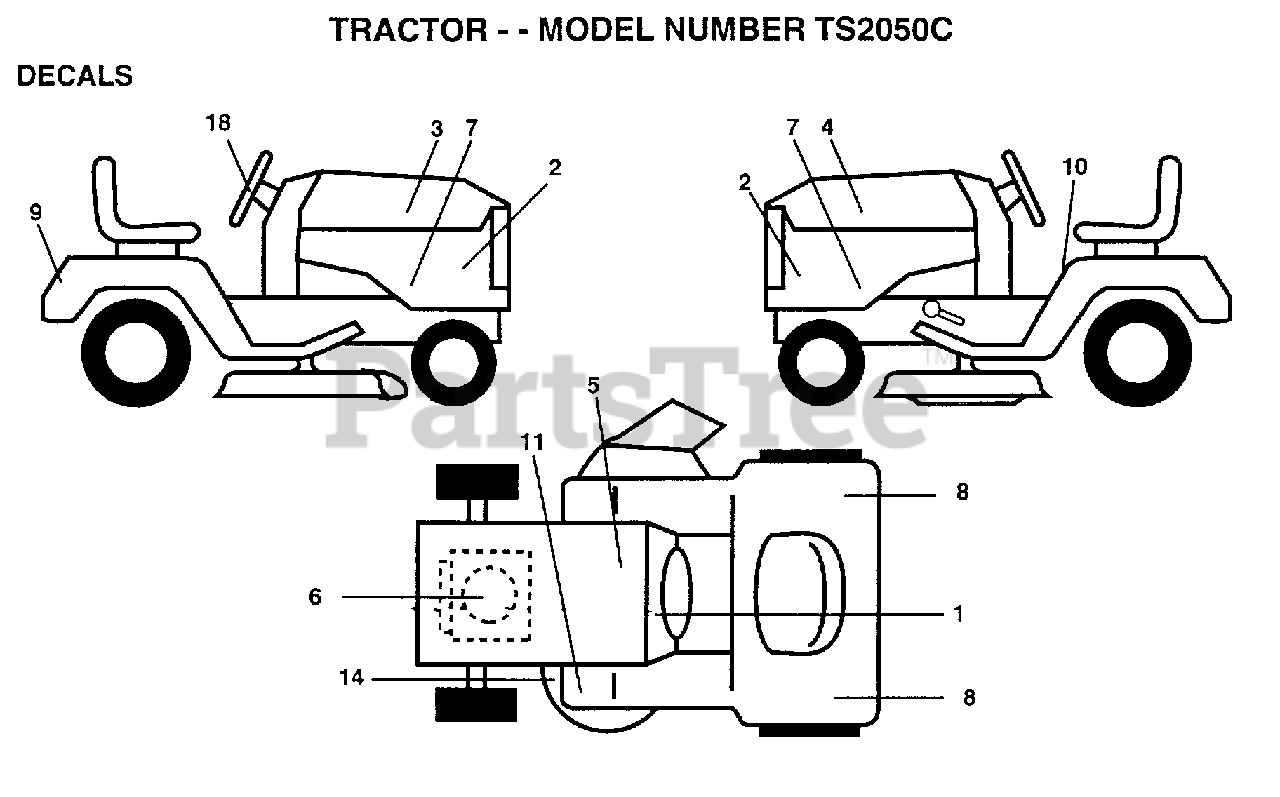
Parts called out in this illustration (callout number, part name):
1	DECAL.DASH.INST.
2	NAMEPLATE.HUSK.LG
3	DECAL.HD.RH.20/50
4	DECAL.HD.LH.20/50
5	DECAL.BTRY.DANGER
6	DECAL KOHLER 20 OHP DMD
7	DECAL.PNL.SIDE.20
8	REFLECTOR-TAIL YT
9	DECAL.FEND.YT/GT
10	DECAL
14	"DECAL.V.BELT.44"""
18	DECAL.INS.STG.WHL
